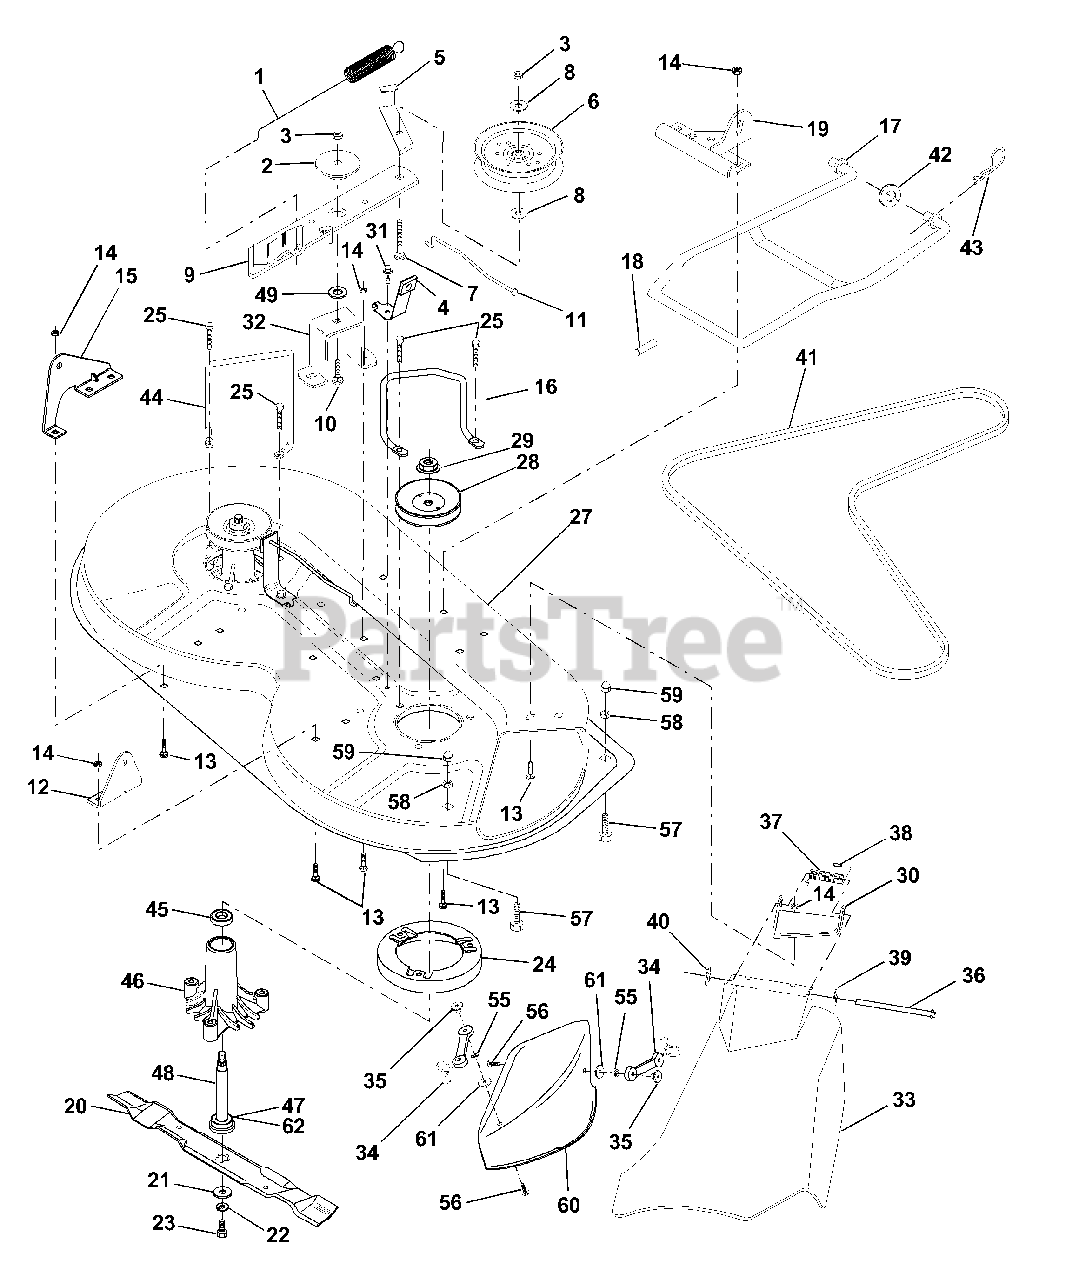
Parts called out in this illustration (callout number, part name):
1	Spring, Mower Clutch
2	Spacer, Retainer
3	Nut, Crownlock 3/8-16
4	Brake Asm.
5	Guide, Belt Idler
6	Pulley, Flat Idler
7	Bolt, Carr. 3/8-16 x 1-3/4 Gr. 5
8	Washer 13/21 x 7/8 x 10 Ga.
9	Arm Asm., Idler Mower
10	Bolt, Carriage 3/8-16 x 1-1/4
11	Rod, Brake
12	Bracket, Lift R. H. Rear
13	Bolt, Carriage 5/16-18 x 3/4
14	Nut, Crownlock 5/16-18
15	Bracket, Lift L. H. Rear
16	Keeper, R. H.
17	Link, Asm. Mower Stabilizer
18	Pin, Drive
19	Bracket, Asm. Front
20	Blade Mulching
21	Washer, Hard
22	Washer, Lock 3/8
23	Bolt 3/8-24 x 1-1/4 Gr. 8
24	Stripper
25	Screw Thdrol Wsh Hd
27	Deck Assembly
28	Pulley, Mandrel
29	Nut, Flangelock 9/16
30	Bracket, Asm. Deflector
31	Screw, Hex Wsh. Thdrol. 5/16-18 x 1/2
32	Arm, Support Idler Mower
33	Deflector
34	Latch Asm, Bagger/Mulch
35	Nut, Weld
36	Rod, Hinge
37	Spring, Torsion Deflector
38	Cap, Sleeve
39	Washer 11/32 x 5/8 x 16 Ga.
42	Washer 11/32 x 5/8 16 Ga.
43	Retainer, Spring
44	Keeper, L. H.
46	Housing Mandrel Vented
48	Shaft, Mandrel
49	Washer, Hardened
55	Washer, Lock
56	Screw
57	Bolt, Fin Hex 5/16-18 x 1
58	Nut, Lock Hex w/Ins. 5/16-18
59	Nut, Acorn Hex 5/16 x 18
60	Cover, Mulching
62	Washer Felt
